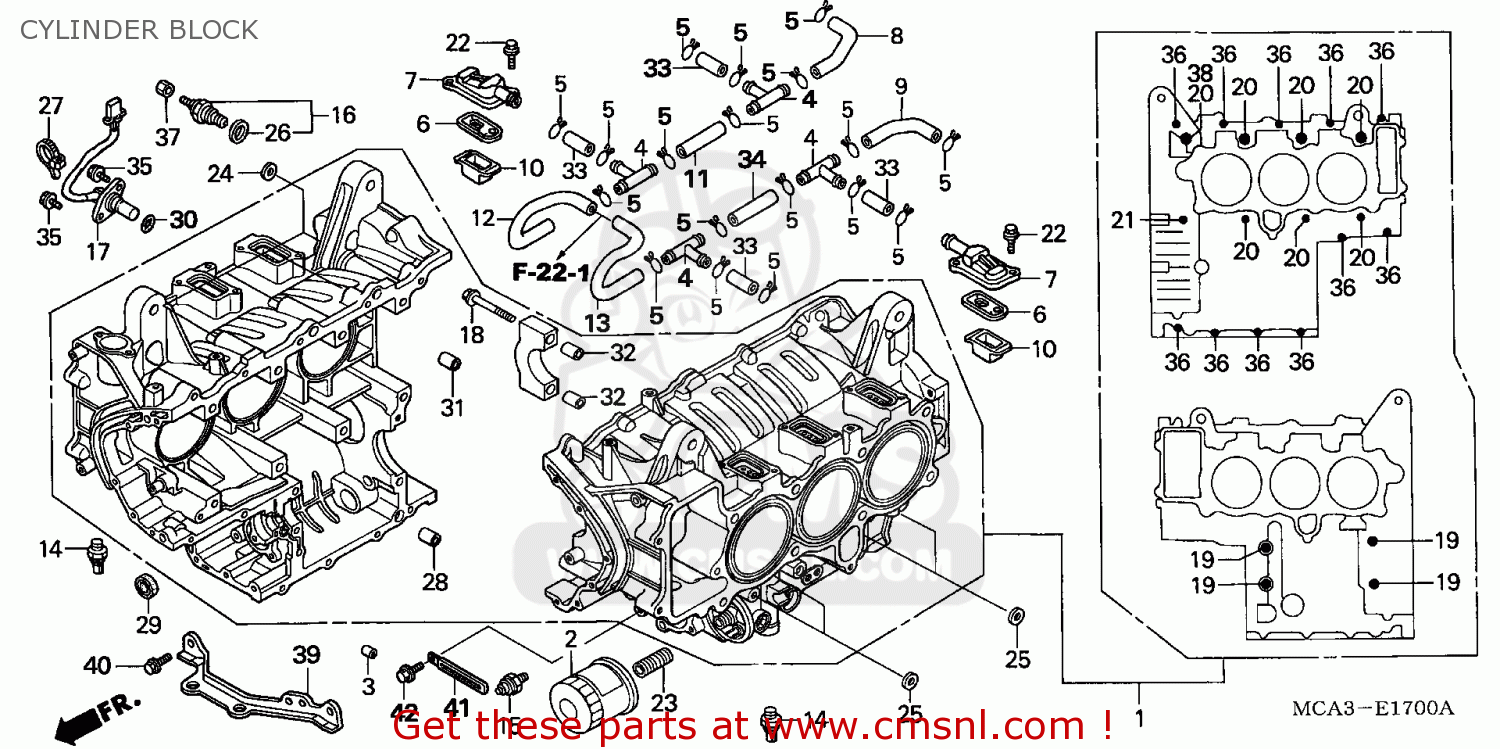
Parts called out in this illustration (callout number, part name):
1	BLOCK ASSY,CYLN
2	OIL FILTER CARTRI
3	ORIFICE,1.7MM
4	JOINT,BREATHER TH
5	CLIP,BRTHR.TUBE
6	REED VALVE COMP
7	COVER,REED VALVE
8	TUBE,R AI
9	TUBE,L AI
10	PLATE,AI PORT
11	TUBE,E
12	TUBE AI B
13	TUBE AI C
14	SENSOR ASSY,KNOCK
15	SW ASSY,OIL PRESS
16	SWITCH
17	SENSOR ASSY,SPEED
18	BOLT,UBS 12X77.5
19	BOLT,FLANGE,8X135
20	BOLT FLANGE 10X12
21	BOLT,FLANGE 10X19
22	BOLT,FLANGE,5X14
23	BOSS, OIL FILTER
24	WASHER SPECIAL
25	WASHER SEALING 8
26	WASHER,NEUTRAL
27	BAND,WIRE
28	COLLAR, 15X20
29	OIL SEAL,8X25X8
30	O RING,18.1X3.6
31	DOWEL,PIN,12X20
32	DOWEL,PIN,4X6.5
33	TUBE,12X42
34	TUBE,12X70
35	BOLT,FLANGE,6X16
36	BOLT,FLANGE,6X35
37	NUT HEX 4MM
